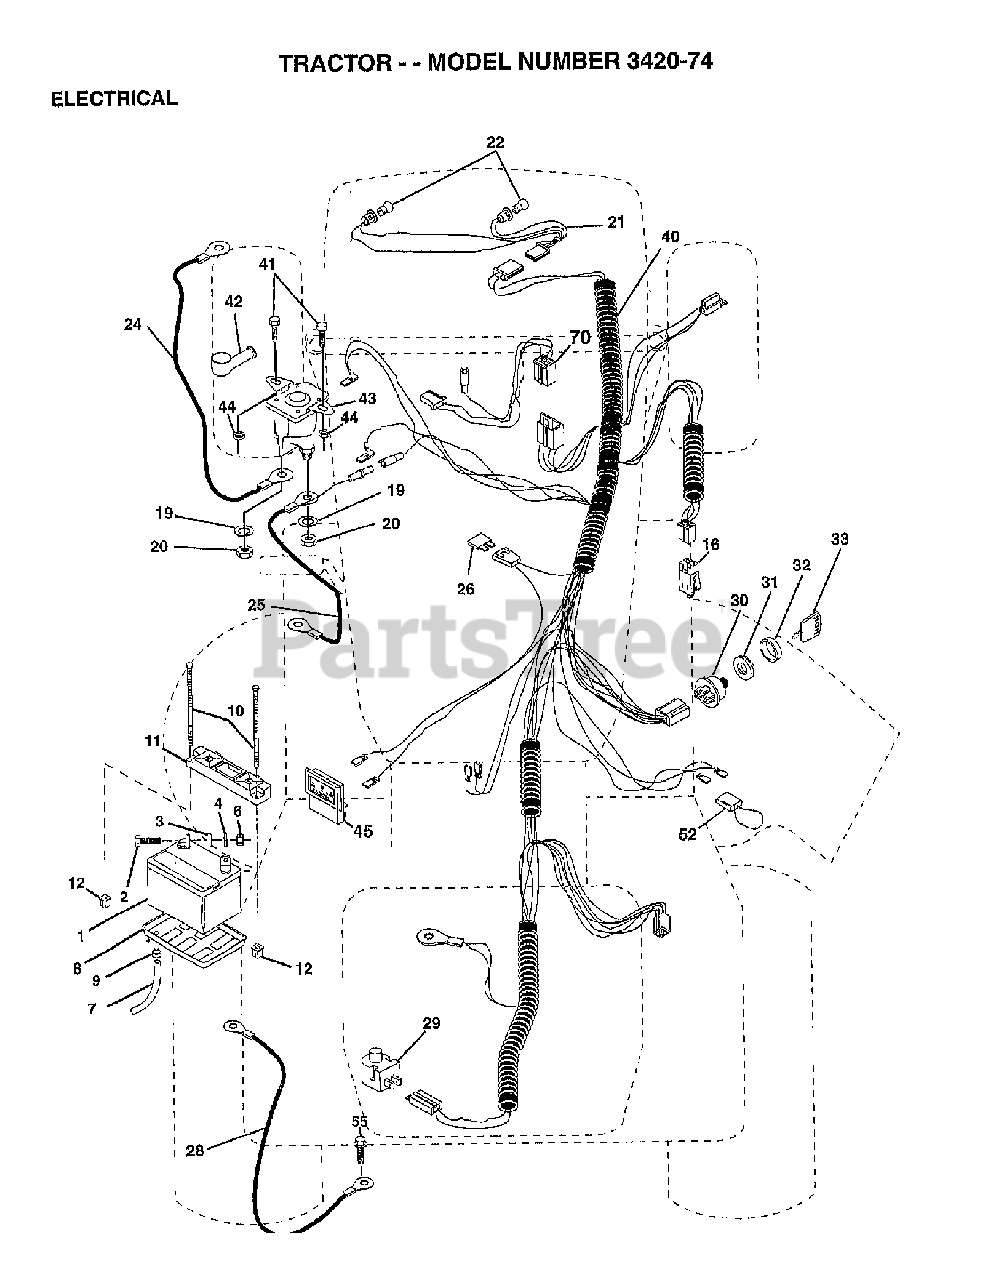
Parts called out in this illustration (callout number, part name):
2	BOLT.HEX.1/4.X.3/4.DICHROMATE
3	WASHER
4	LOCKWASHER
6	NUT
7	BATT DRAIN TUBE T
8	TRAY.BATTERY
9	HOSE CLAMP T
10	BOLT 1/4-20 X 7.5
11	BATTERY HOLDDOWN
20	NUT
22	LIGHTBULB
24	BATTERY CABLE
25	CABLE BATTERY 6 GA 22" W/16W
26	FUSE *
28	CABLE GROUND 6 GA 21" 90T BLK
29	SWITCH SEAT
30	SWITCH.IGNITION.4.POSITION
31	NUT
32	COVER KEY IGNITIO
33	KEY.MOLDED.GENERIC
41	BOLT
42	TERMINAL COVER
43	Solenoid Kit, .95
44	NUT.HEX.KEPS.1/4-20
45	AMMETER
52	WIRE PROTECTION LOOP
55	SCREW LT
70	HARNESS, ENGINE
